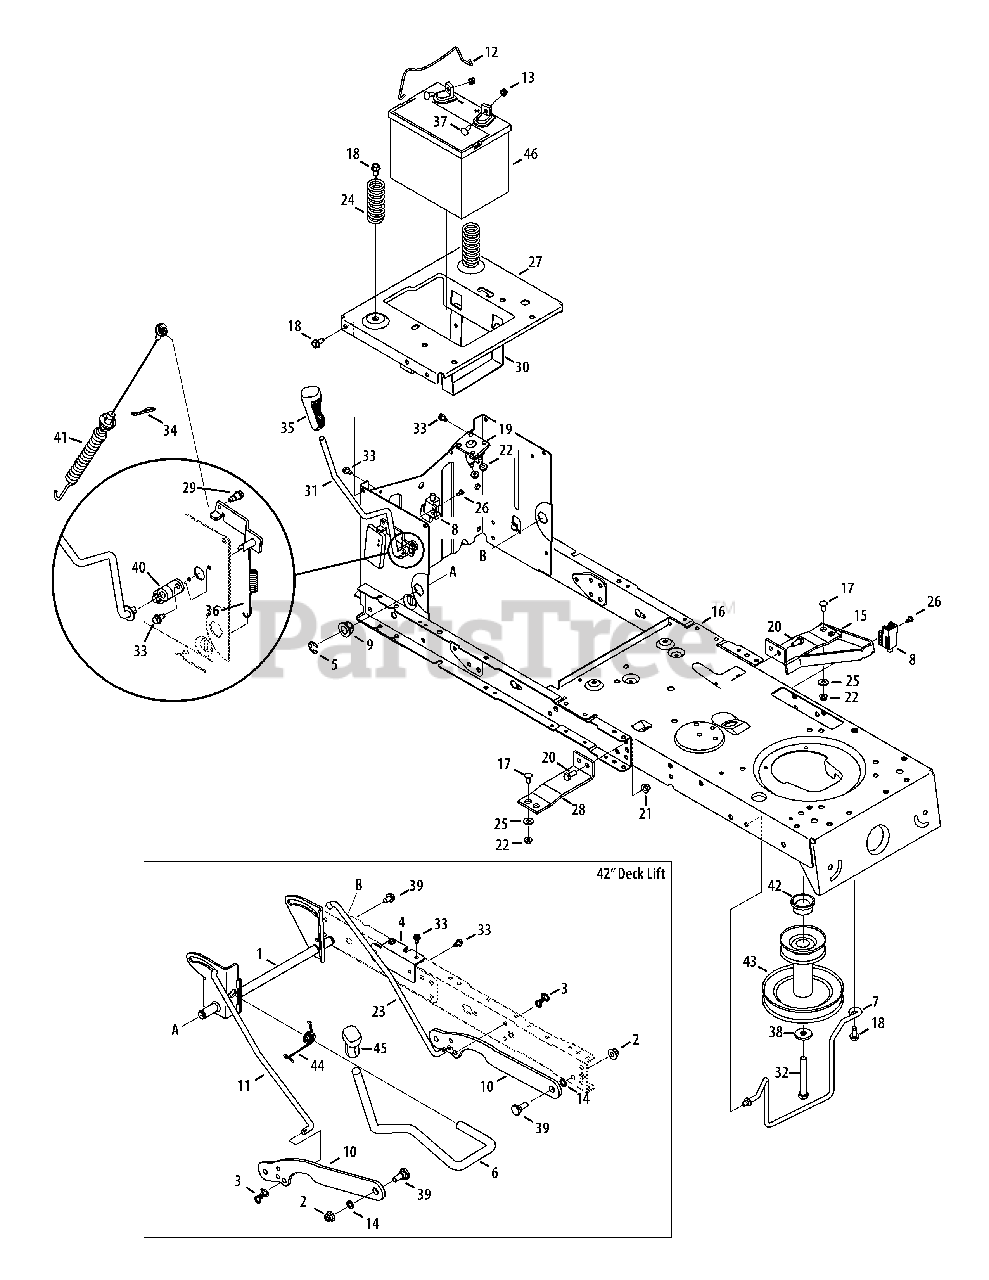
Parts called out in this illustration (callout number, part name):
1	Shaft Assembly Lift
2	Nut, Flange Lock, 3/8-16, GrF
3	Pin, Cotter, Bow Tie
4	Frame Brace Bracket
5	Ring, E-Type, .625 Dia.
6	Deck Handle, Lift, 46" Deck
7	Rod, Belt Keeper
8	Switch, Interlock
9	Bearing, Hex Flange
10	Deck Lift Link
11	Lift Rod, RH
12	Battery Hold Down Rod
13	Nut, Sems, 1/4-20
14	Washer, Flat, .385 x .62 x .063
15	Support Bracket Assembly
16	Frame Assembly
17	Screw Carriage, 1/4-20 x .75
18	Screw, 5/16-18, .750
19	12V Solenoid
20	Hex Screw, 5/16-18 x .75
21	Flange Lock Nut, 5/16-18
22	Nut, Flange Lock, 1/4-20, GrF
23	Lift Rod, LH
24	Compression Spacer, 1.314 x 2.55
25	Flat Washer, .28 x .74 x .063
26	Shoulder Screw, #10-32 x .500
27	Seat Bracket, Frame
28	Bracket, Runing Board
29	Shoulder Bolt, 1/4-28 x .342 x .335
30	Bracket, Battery
31	PTO Handle Assembly
32	Hex Screw, 7/16-20 x 3.25
33	Screw, 1/4-20, 0.500
34	Pin, Click, .092 x 1.64
35	Grip, Handle, 3/8
36	Spring, Extension
37	Screw, Carriage, 1/4-20, .75, Gr5
38	Washer, Flat, .450 x 1.250 x .164
39	Bolt, Shldr. .500 x .270 3/8-16
40	Bearing, PTO
41	Deck Engage Cable
42	Spacer, 1.010 x 1.400 x .825
43	Engine Pulley
44	Spring, Torsion 46" Deck
45	Grip, Handle, 5/8
46	Battery
